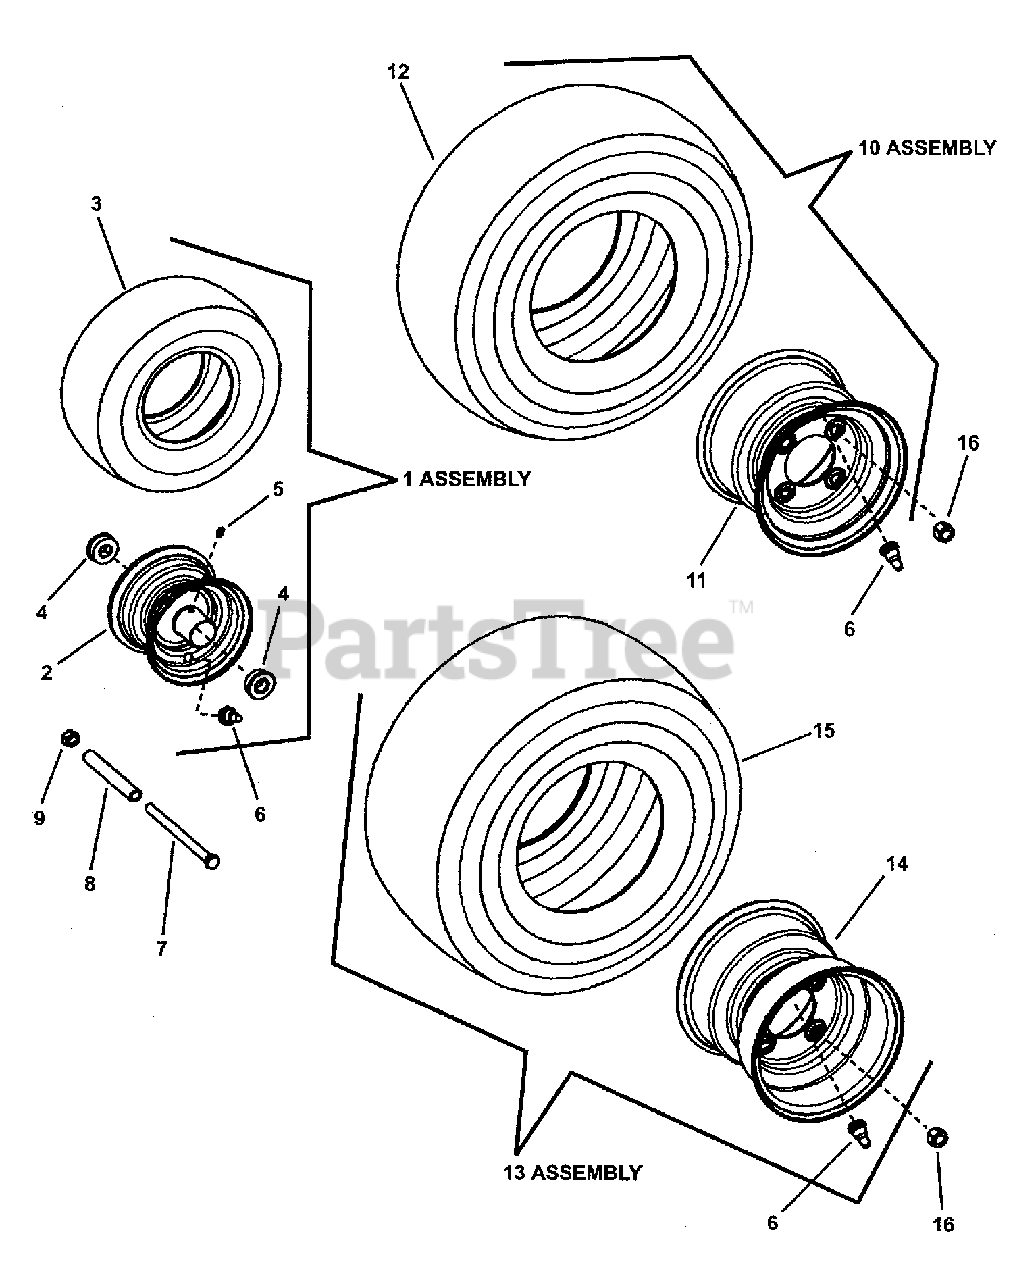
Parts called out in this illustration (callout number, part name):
1	WHEEL ASSEMBLY, HOZ
2	RIM, Caster Wheel
3	TIRE, 11 x 4.00-5, Smooth Tread
4	BALL BEARING, .625 x 1.38
5	GREASE FITTING, 1/4-28 Thread forming
6	VALVE STEM, Snap In
7	CAPSCREW, Hex Head, 7/16C X6 GR5 YZ
8	SPACER, 5/8 OD
9	NUT, Hex Center Lock, 7/16C GR5 ZP
10	WHEEL ASSEMBLY, 18 X 6.50-8, Turf Master
11	RIM, 18 x 6.50, 4 Bolt
12	TIRE, 18 x 6.50-8, Turf Master
13	WHEEL ASSEMBLY, 18 X 8.50-8, Turf Master
14	RIM, 18 x 8.50, 4 Bolt
15	TIRE, 18 x 8.50-8, Turf Master
16	LUG NUT, 1/2-20 YZ
